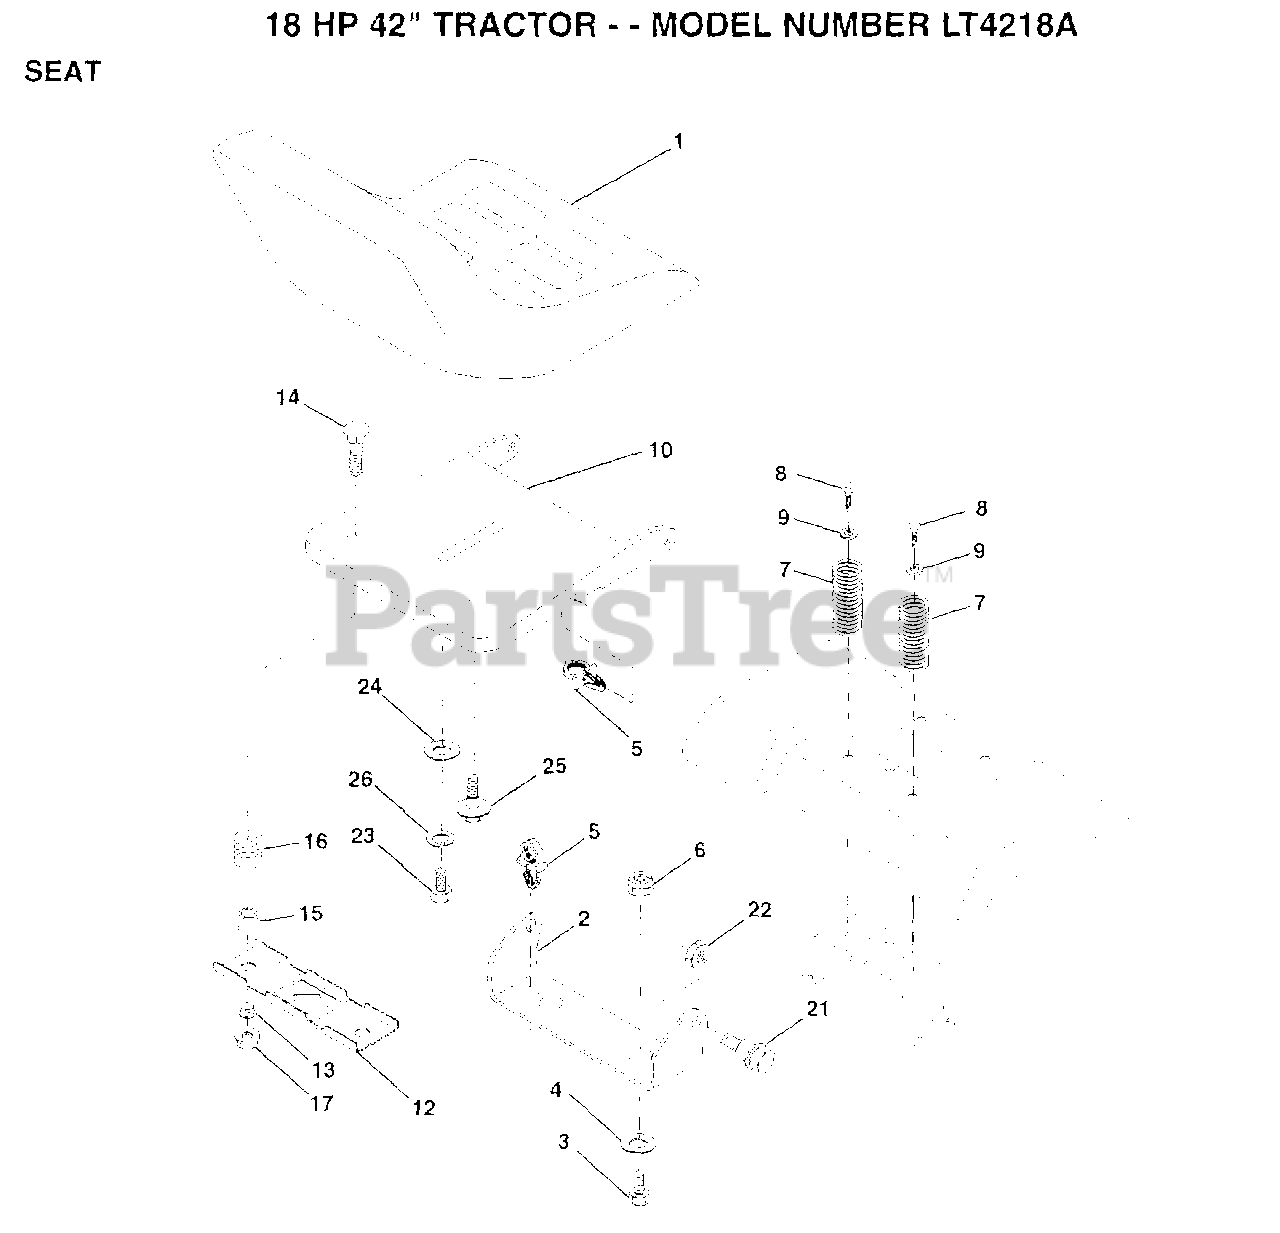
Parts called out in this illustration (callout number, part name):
2	BRACKET PVT SEAT
3	BOLT
4	WASHER PM
5	CLIP PUSH - IN
6	NUT
7	SPRING COMPRESSIO
8	SCREW GTV
9	WASHER
12	BRKT SWITCH
13	BUSHING
15	SPACER SPLIT
16	SPRING COMPRESSED
21	BOLT.SHLD.5/16-18
23	BOLT
24	WASHER
25	"BOLT,SHOULDER"
26	LOCKWASHER
